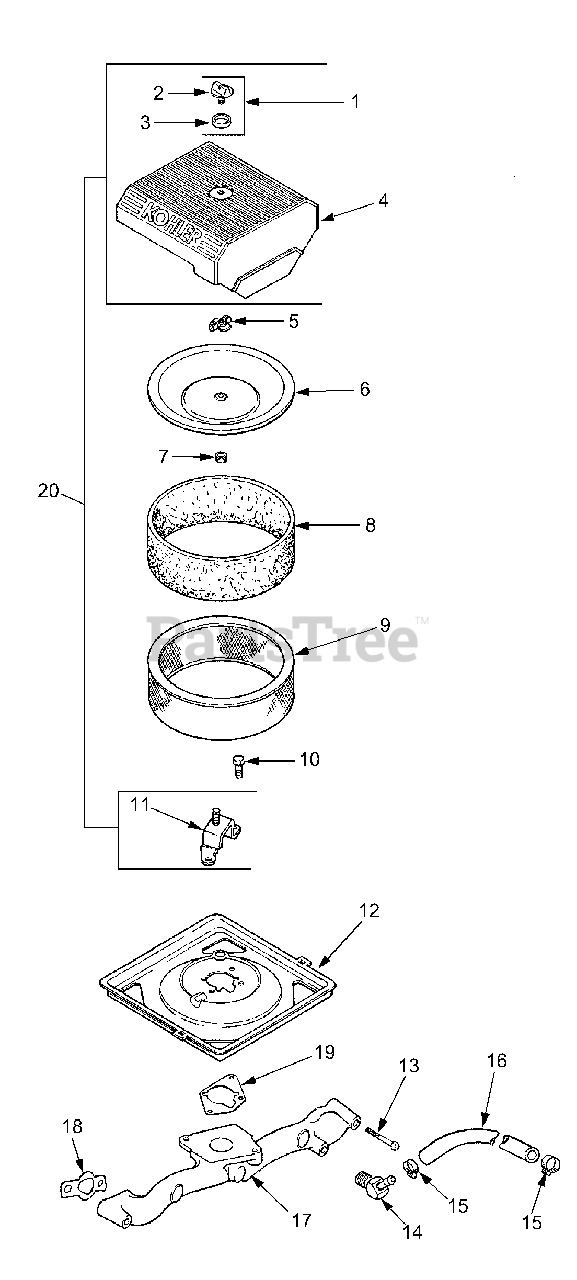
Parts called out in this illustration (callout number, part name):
1	Kit, Knob w/Seal
3	Seal, Air Cleaner Cover Knob
4	Cover, Air Cleaner
6	Cover, Inner Air Cleaner
7	Seal, Inner Air Cleaner
8	Precleaner, Element
9	Element, Air Cleaner
10	Screw, Hex Flange M6 x 1.0 x 16
11	Bracket, Air Cleaner Base
12	Base, Air Cleaner
13	Screw, Hex Flange M6 x 1.0 x 55
14	Connector, Hose 45°.
15	Clamp, Hose
16	Line, Fuel 17"
17	Manifold, Intake
18	Gasket, Intake Manifold
19	Gasket, Air Cleaner Base
20	Kit, Air Cleaner Cover
